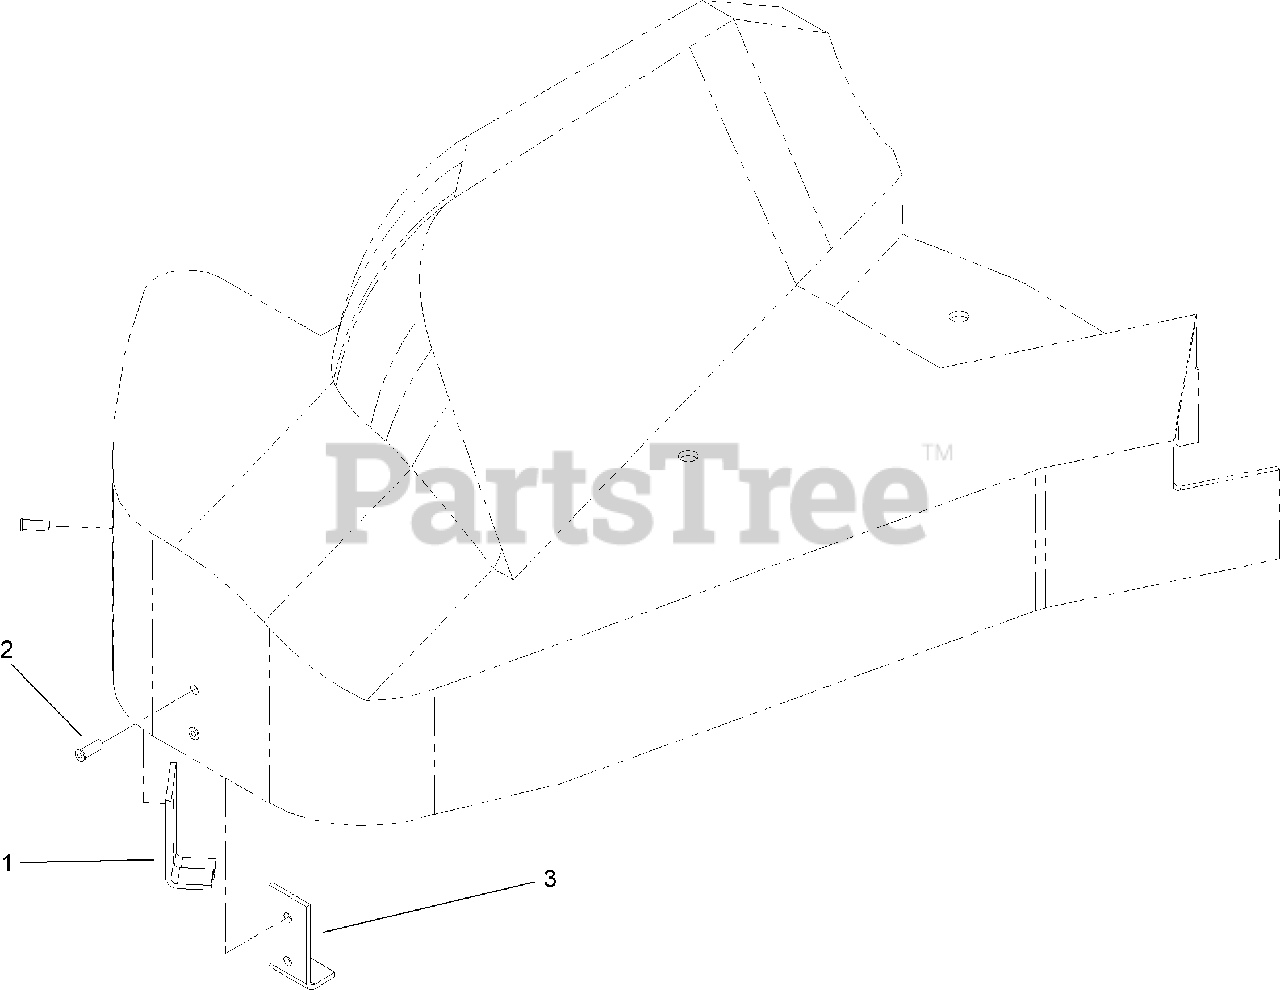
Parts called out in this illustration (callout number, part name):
1	BRACKET-SUPPORT, SHIELD
2	RIVET-POP
3	BRACKET-SUPPORT, SHIELD
